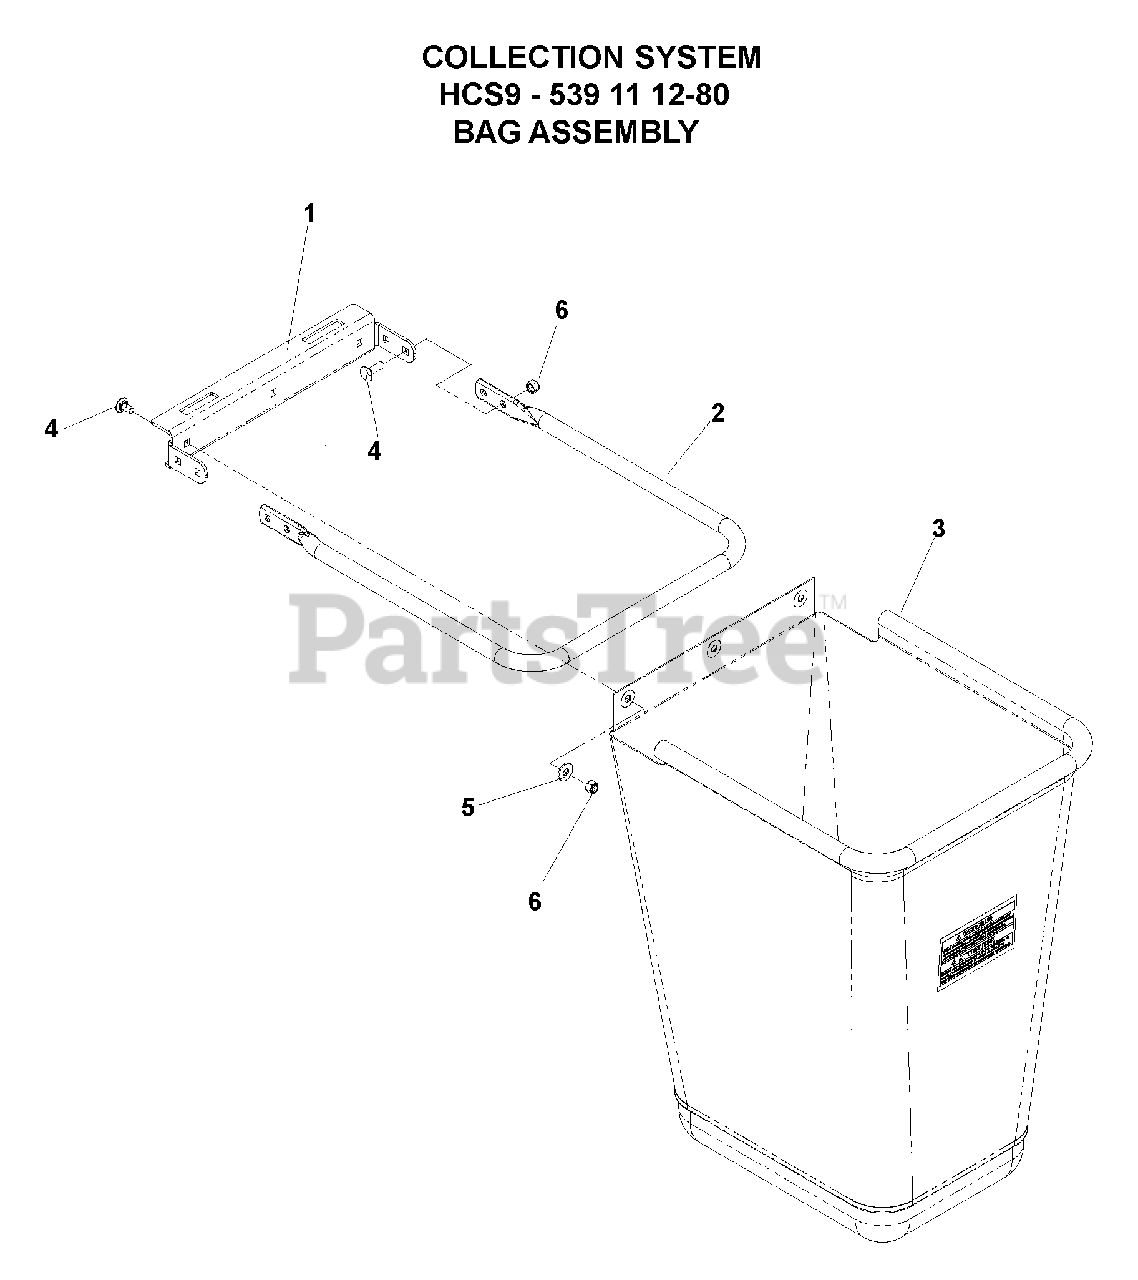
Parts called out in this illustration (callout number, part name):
1	HANGER, BAG
2	TUBE, BAG FRAME
3	BAG, SMALL
4	RHSNB, 5/16-18 X 3/4, GR5
5	WASHER, 5/16
6	NUT, 5/16-18, NYLOC
539111280	Bag Assembly Collection System
